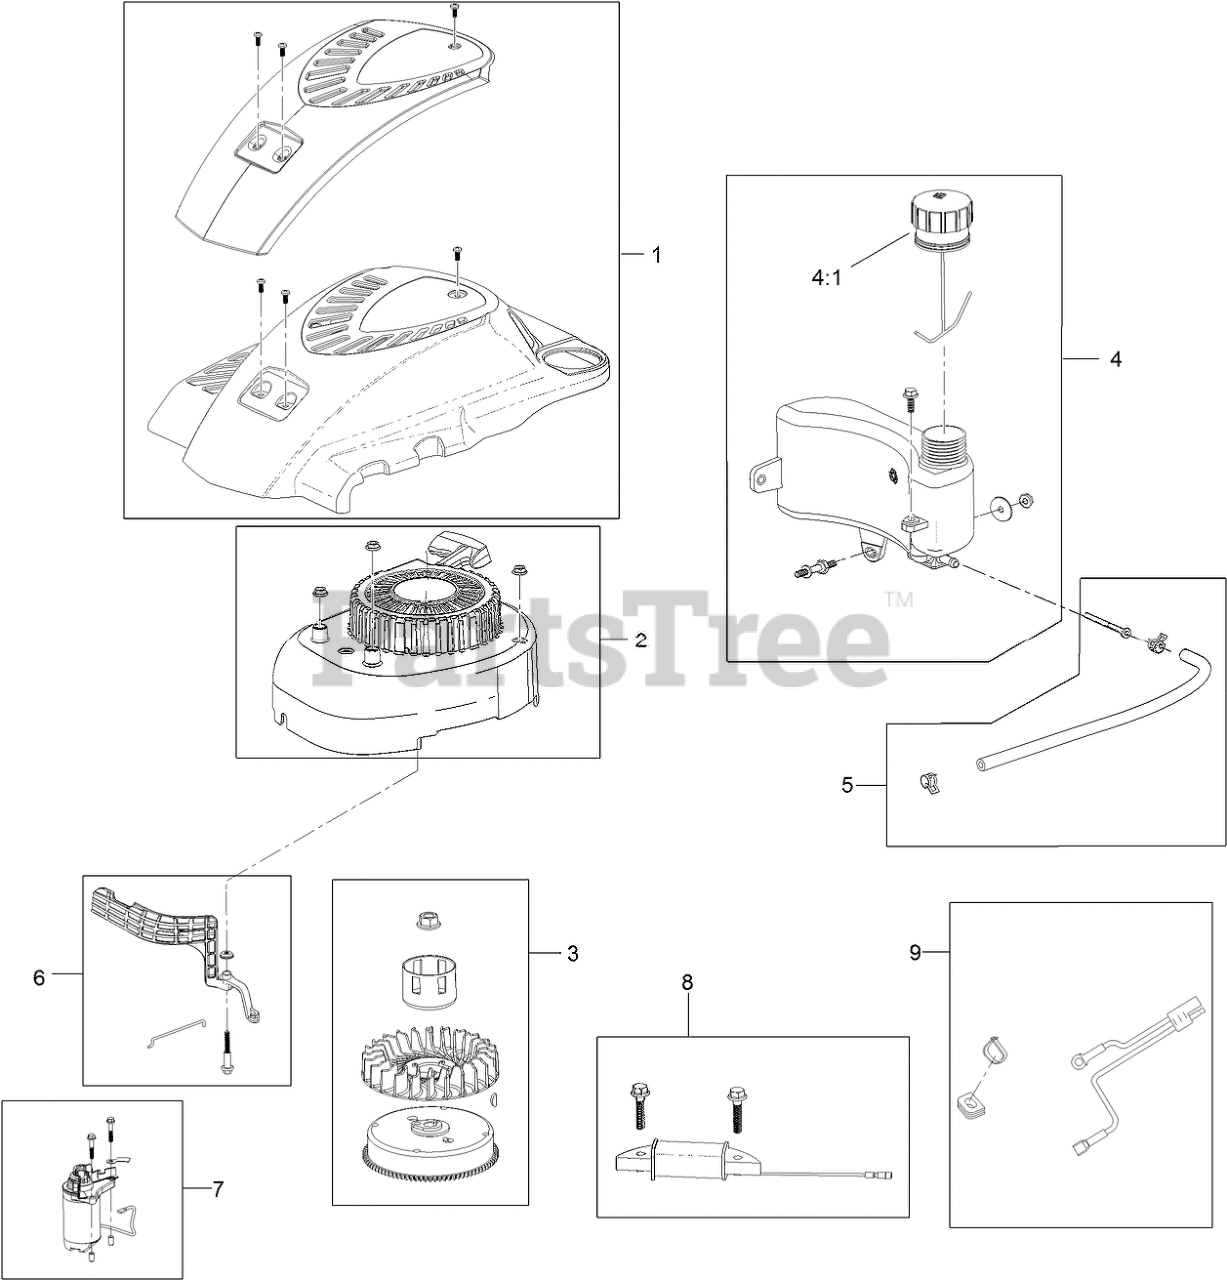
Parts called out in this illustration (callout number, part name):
1	Shroud ASM
2	RECOIL AND BLOWER SHROUD KIT
3	FLYWHEEL AND FAN KIT
4	FUEL TANK KIT
4:1	CAP-FUEL
5	FUEL LINE KIT
6	AIR VANE KIT
7	STARTER KIT
8	ALTERNATOR KIT
9	WIRE HARNESS KIT
